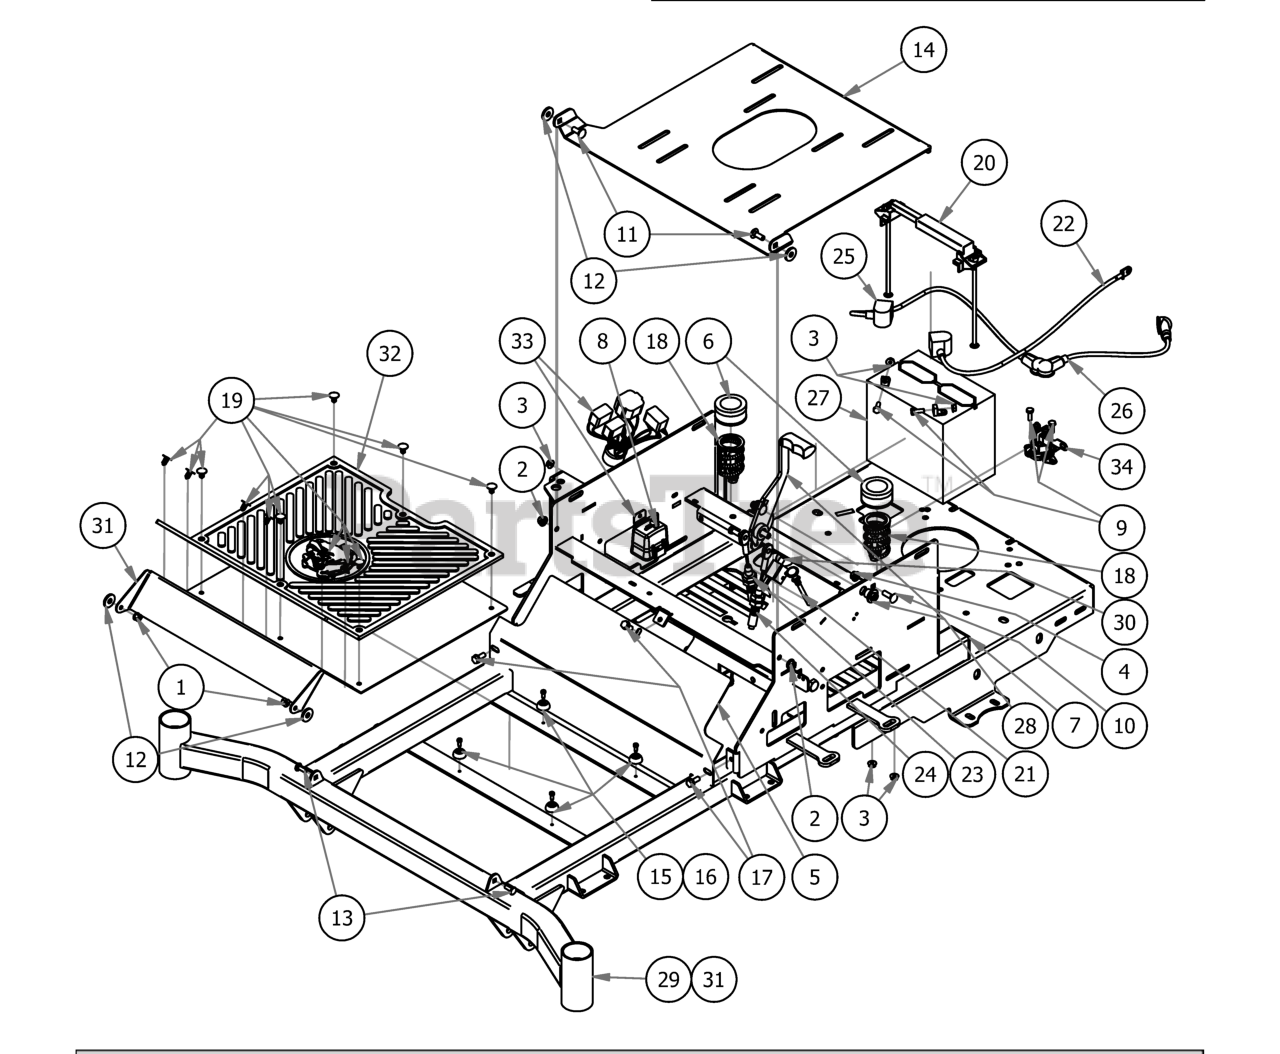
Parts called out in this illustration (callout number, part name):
1	1/4-20 Nylon Insert flange Nut
2	5/16" Nylon Flange Nut
3	1/4-20 Hex Flange Nuts Zinc w/Serrations
4	5/16" Flange Nut
5	2017 ZT Cooler Cover
6	Seat Spring Cap Cover
7	2x2 Square Plug
8	1/4" x 1/2" BS C/S 18-8 SS
9	1/4" x 3/4" Hex Bolt
10	5/16" x 1" Carriage Bolt
11	5/16" x 7/8" Carriage Bolt
12	.360 ID Plastic Washer
13	1/4" x 3/4" Carriage Bolt
14	2017 MZ Seat Plate
15	Button Bumper
16	#10 x 1/2" Self Tapping Screw
17	5/16 x 3/4 washer head type F screw
18	Seat Spring Assembly
19	5/8" Christmas Tree Fastener
20	Hold Down Assembly
22	Ground Cable
23	Brake Cable,18.5"
24	Brake Cable, 24.5"
25	24" Red Battery Cable
26	12" Red Battery Cable
28	2017 ZT Brake Handle Assembly
29	2017 MZ/ZT 54"-60" Frame
30	Safety Switch
31	MZ/ZT 2017 Floorboard
32	2017 MZ/ZT Floor Mat
33	Wiring Harness
